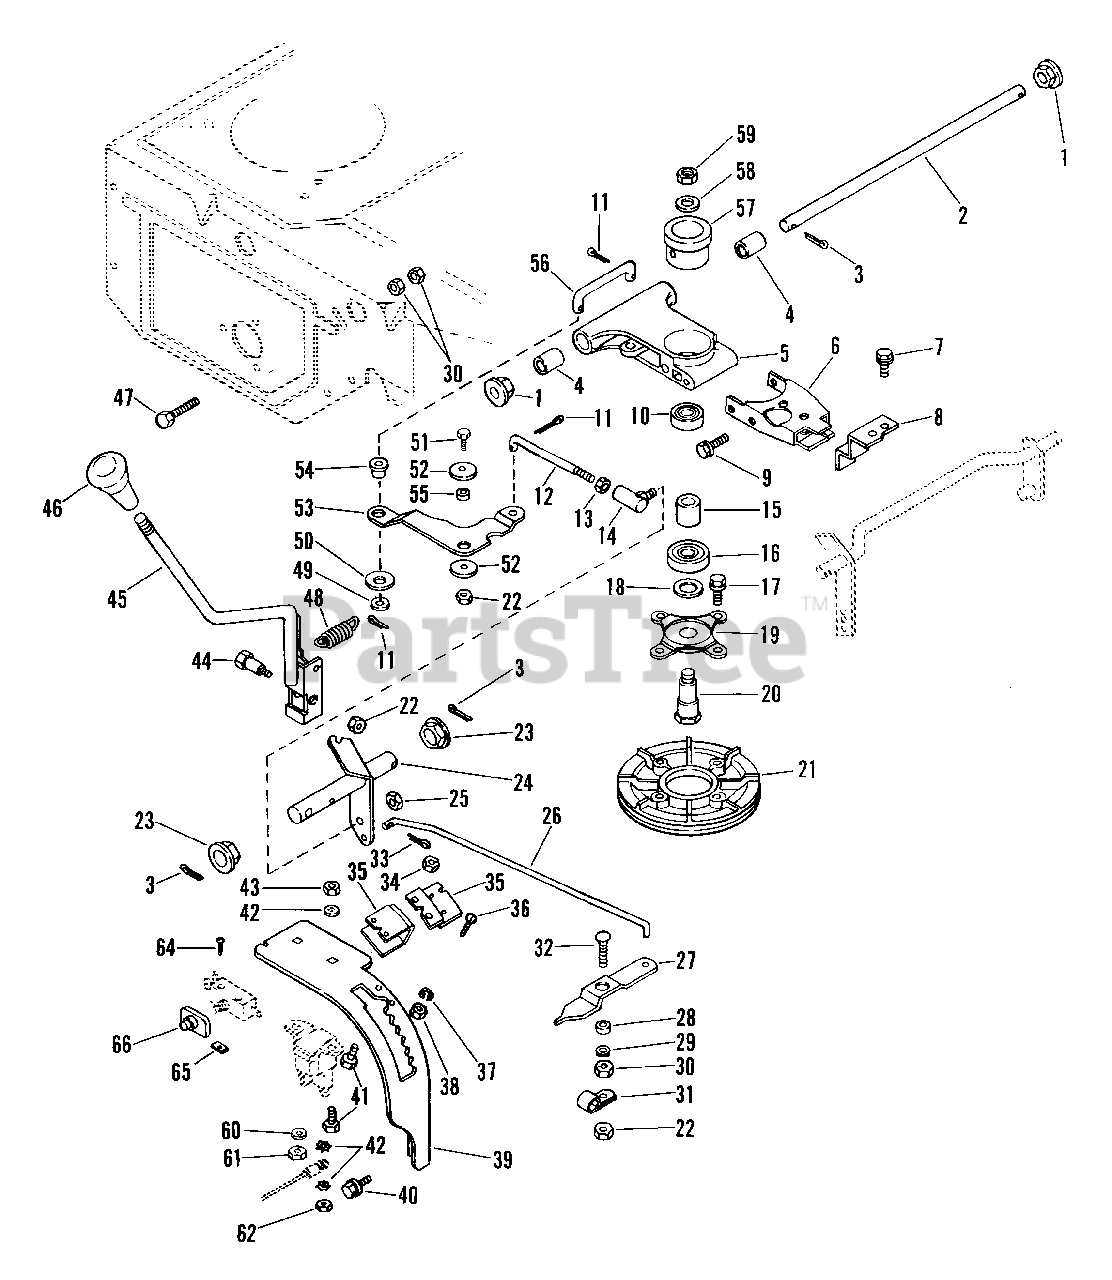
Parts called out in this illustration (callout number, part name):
1	FLANGE BUSHING
2	TRANSFER SHAFT
3	PIN-COTR .12X1.0 PL
4	BSHG-SLV .625X.750X.500 BR
5	CARRIER ASSEMBLY
6	CARRIER YOKE
7	SCR-TAP .312-18X.50 HWH PL TR
8	NEUTRAL STOP
9	SCR-TAP .312-18X.75 HWH PL TR
10	BRG-BALL .625X1.375X.44
11	PIN-COTR .09X.75 PL
12	SHIFT ROD
13	NUT-HEX .312-24 PL
14	SNAP IN BALL JOINT
15	BSHG-SLV .634X1.000X.465
16	BRG-BALL .750X1.781X.61
17	SCR-TAP.250-20X.62 HWH BLK ZC
18	WSHR-HDND-THRST .758X1.23X.031
19	DISC ADAPTER
20	SPINDLE BOLT
22	NUT-LK .312-18 GR A PL
23	FLANGE BUSHING
24	SHIFT ARM
25	NUT-LK-CTR .312-24 PL
26	INDICATOR ROD
27	INDICATOR
28	SPACER BUSHING .5 X .32 X .163
29	WSHR-FL-STL .323X.625X.062 PL
30	NUT-HEX .312-18
32	BLT-RDHDSQNK .31-18X1.0 SHT PL
33	PIN-COTR .06X.50
34	NUT-LK-CTR .250-20 PL
35	BRACKET NEUTRAL SWITCH
36	SCR-MCH 10-24X1.00 SLRH PL
37	WSHR-LK 10X.047 MED PL
38	NUT-HEX 10-24 PL
39	QUADRANT
40	SCR-TAP .250-20X.50 HXSLHDPL
41	BLT-HEX .25-20X.50 PL GR2
42	WSHR-LK-INT .313X.030 PL
43	NUT-HEX .250-20 PL
44	SHOULDER BOLT .436 X .912
45	SHIFT LEVER
47	BLT-HEX .31-18X1.50 GR2 YWZC
48	SG-TENS .092X.69X1.75 WLD 54
49	WSHR-FL-STL .380X.626X.033
50	WSHR-FL-STL .531X1.250X.100 PL
51	BLT-HEX .31-18X.75 PL GR2
52	WSHR-FL-STL .344X1.125X.063PL
53	BELL CRANK
54	BSHG-FLG .372X.500X.312X.625NY
55	SPACER BUSHING .5 X .32 X .21
56	SHIFT LINK
57	BEARING HOUSING
58	WSHR-HDND-STL-THR.515X.97X.062
59	NUT-LK-CTR .50-20 PL
60	WSHR-LK-EXT #10 ID X .022
61	NUT 10-32 PL
62	NUT-JAM .312-24 PL
63	CABLE TIE LG 5-1/2
64	SCR-MCH 6-32X1.00 SLRH PL
65	NUT-KEPS 6-32 PL
66	SWITCH BOOT
